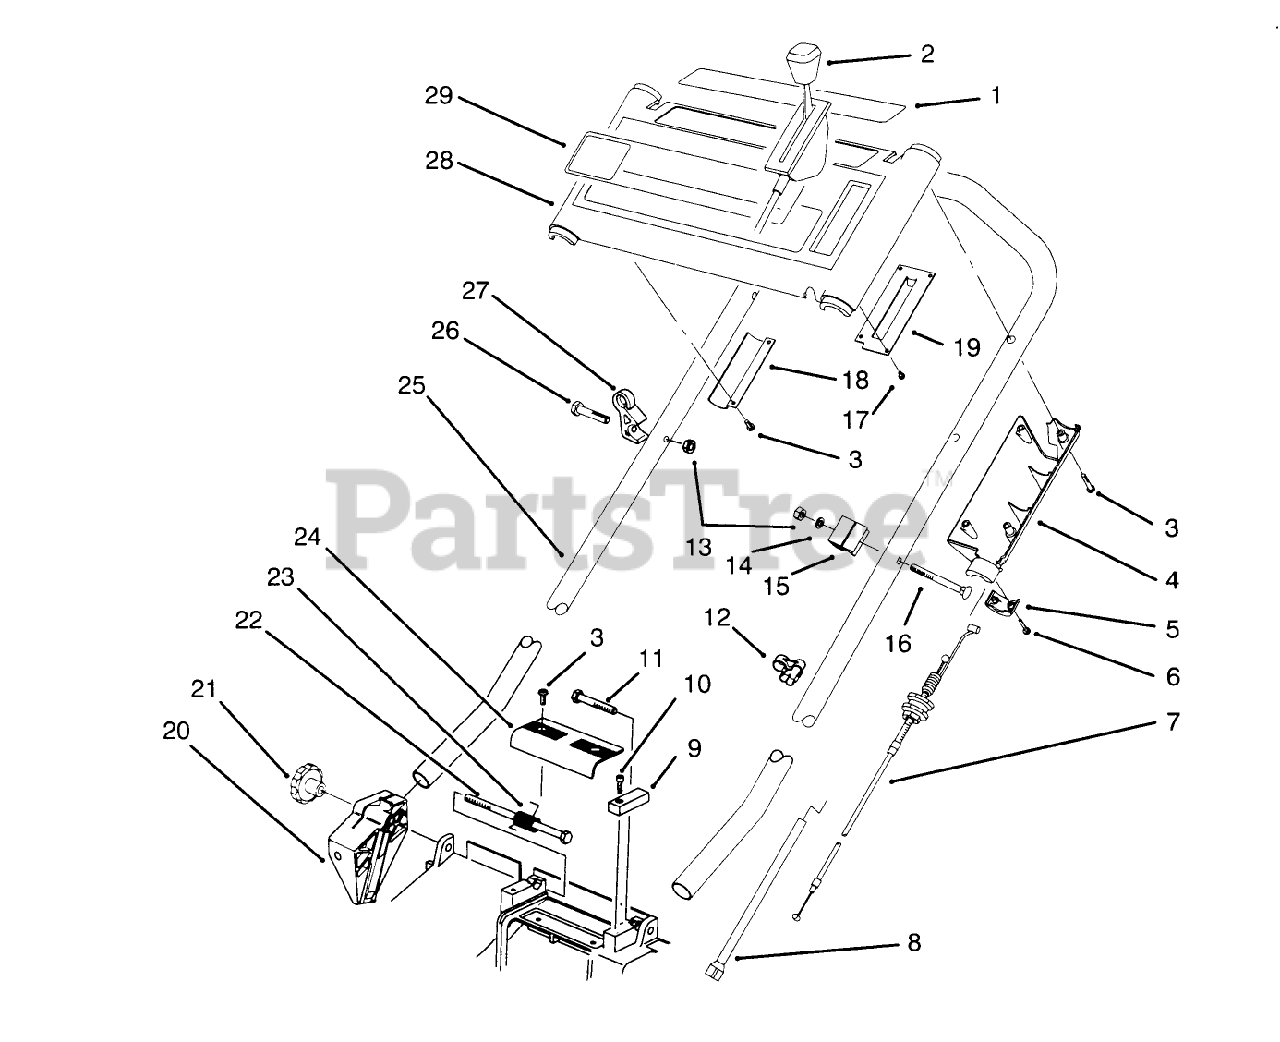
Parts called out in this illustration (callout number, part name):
2	CONTROL - THROTTLE
3	SCREW-PPH, PLASTITE
4	COVER-THROTTLE, LEVER
5	LOWER THROTTLE CAP
8	CABLE - BRAKE
13	NUT-LOCK, NI
14	WASHER-FLAT
15	SUPPORT-CABLE
16	SCREW-HANDLE
20	Mount-Handle R.H.
22	BOLT-LONG
23	SPRING-DOOR
24	GRIP-UPPER
25	HANDLE
27	GUIDE - ROPE
29	DECAL - PANEL
